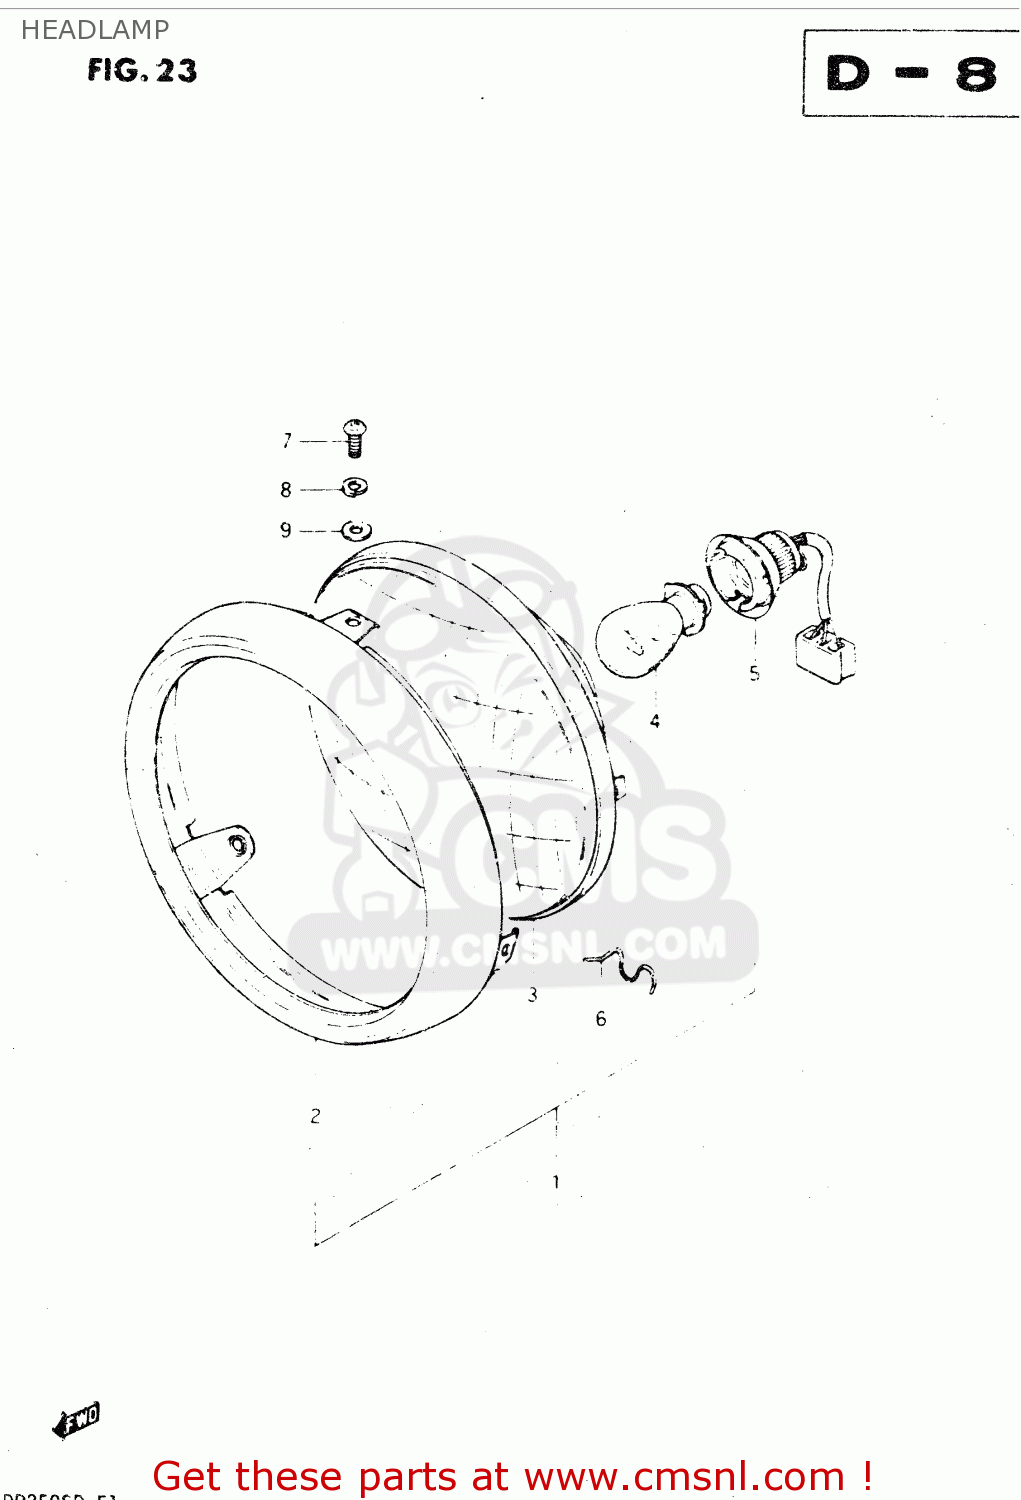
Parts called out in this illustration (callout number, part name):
1	HEADLAMP ASSY
2	RIM
3	UINT
4	BULB(6V,35/35W)
5	SOCKET
6	SPRING
7	SCREW
8	LOCK WASHER
9	WASHER
